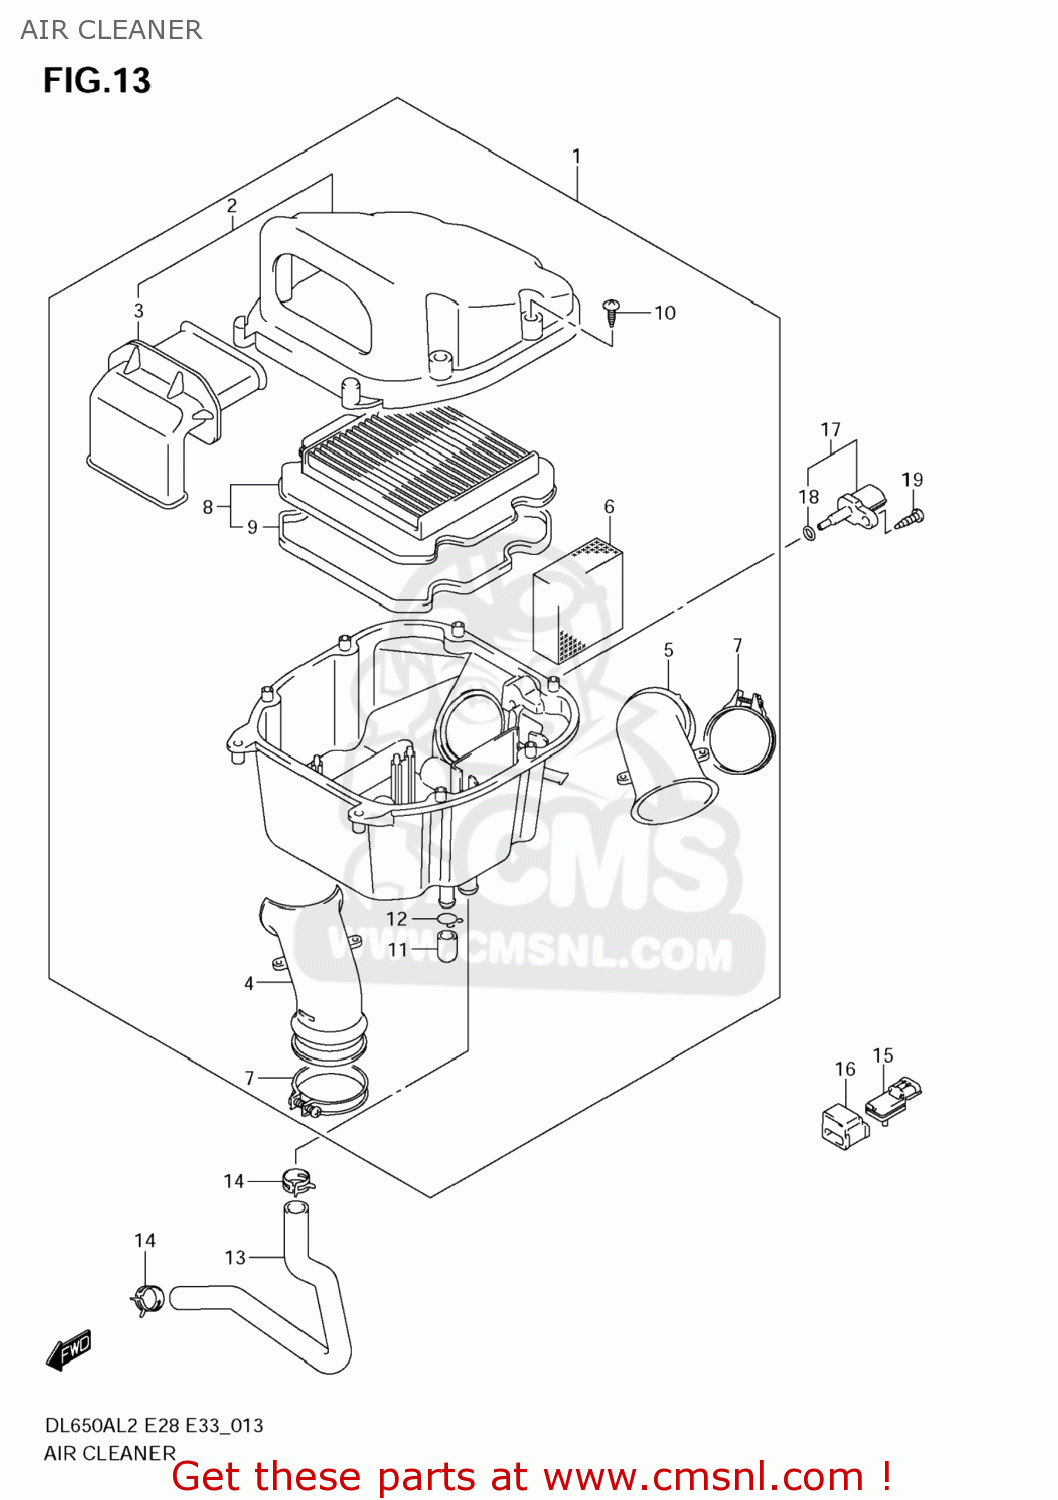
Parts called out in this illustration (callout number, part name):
1	CLEANER ASSY,A
2	CAP,AIR CLEANE
3	TUBE,INLET
4	TUBE,OUTLET
5	TUBE,OUTLET
6	FILTER,BREATHER
7	CLAMP,OUTLET TUBE
8	FILTER ASSY
9	GASKET,AIR CLEANER (NAS)
10	SCREW
11	PLUG
12	CLIP
13	TUBE,BREATHER
14	CLIP
15	SENSOR,PRESSURE
16	HOLDER,SENSOR
17	SENSOR,AIR TEMP
18	O RING
19	SCREW
